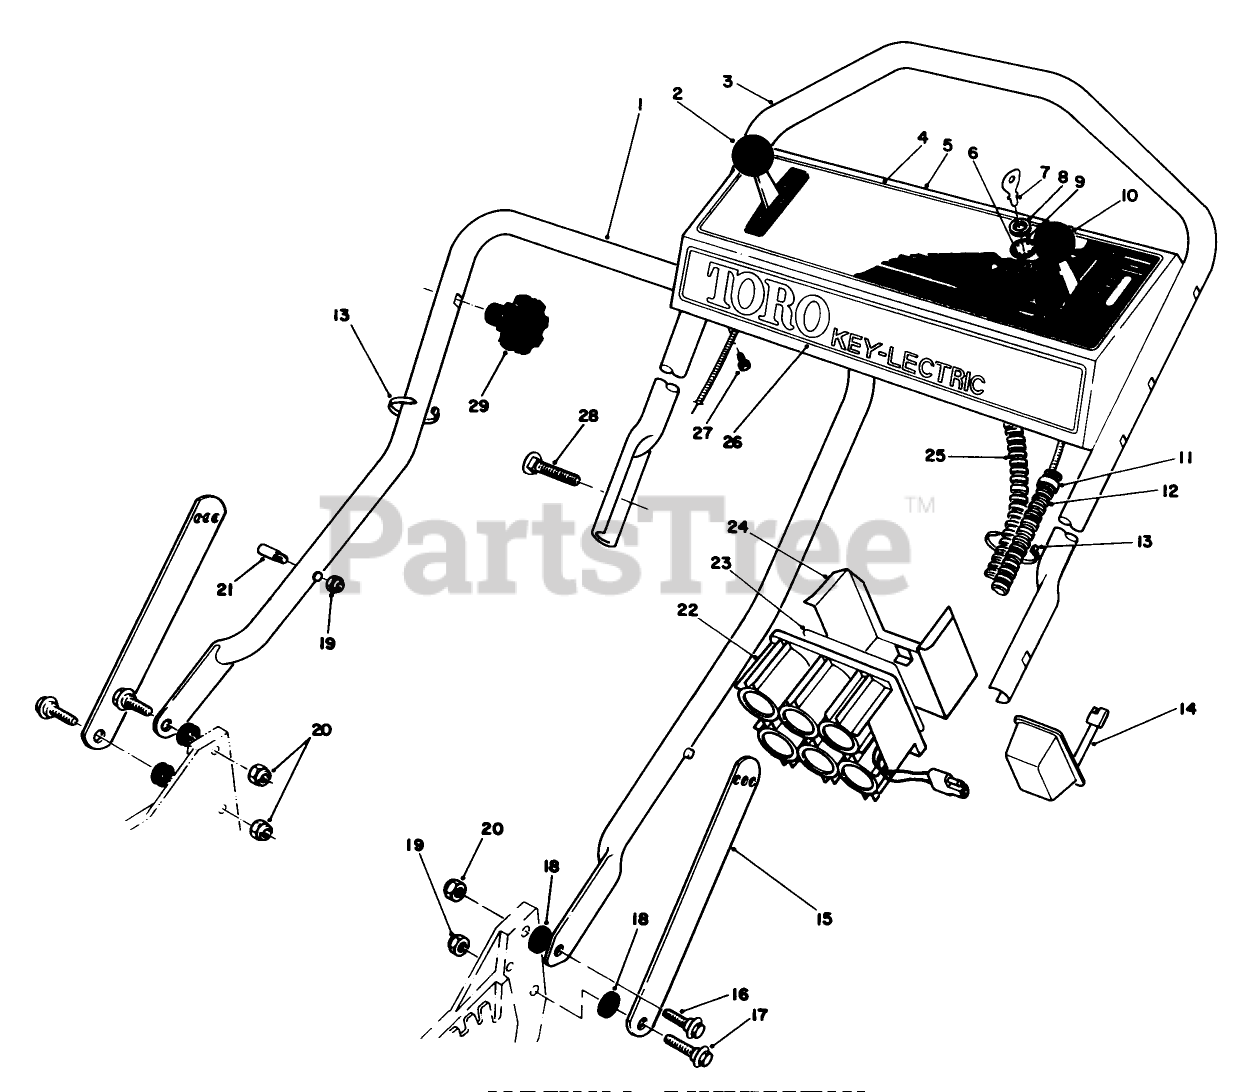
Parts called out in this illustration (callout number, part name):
2	SERVICE THROTTLE CONTRO
6	STARTER SWITCH ASM
8	NUT-HH
9	WASHER-LOCK
10	SERVICE TRACT. CONTROL
11	FITTING-RING
13	TIE-CABLE
16	SCREW-SHOULDER
17	SCREW-SHOULDER
18	SPACER
19	NUT-LOCK, NI
20	NUT-LOCK, NI
21	HANDLE PIN
22	BATTERY ASSEMBLY,WET
25	WIRE HARNESS
27	SCREW-HWHTF
